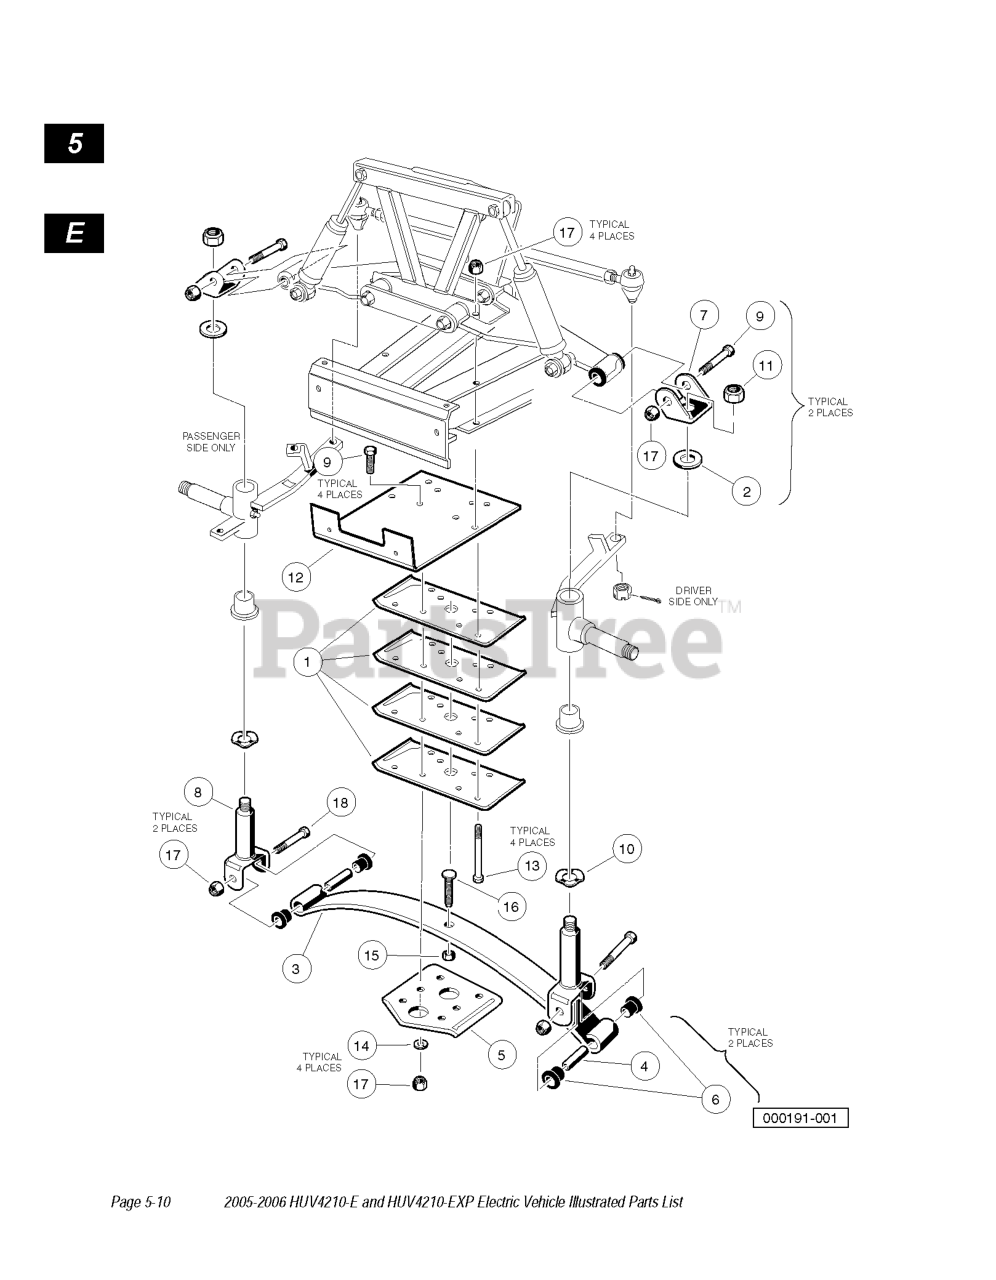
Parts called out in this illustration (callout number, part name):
1	PLATE, SPRING MOUNT
2	BEARING THRUST
3	SPRING, FRONT LEAF
4	BUSHING - STEEL (GAS CAR)
5	PLATE, FRONT SPRING RETAINER
6	BUSHING, URETHANE
7	CLEVIS, DELTA UPPER
8	ASM, DELTA KINGPIN
9	SCREW, 3/8-16 X 2.75 HX HD CAP
10	WASHER, 1.125 OD WAVE
11	LOCKNUT, 1/2-20 NYLON INSERT
12	SUPPORT-BRUSH GUARD
13	SCREW, 3/8-16 X 5.50 HX HD CAP
14	WASHER,LOCK,HEL SP 3/8 REG
15	NUT, HEX 3/8-16
16	SCREW, ECCENTRIC ADJUSTMENT
17	LOCKNUT, 3/8-16 HEX
18	SCREW, 3/8-16 X 3.375
